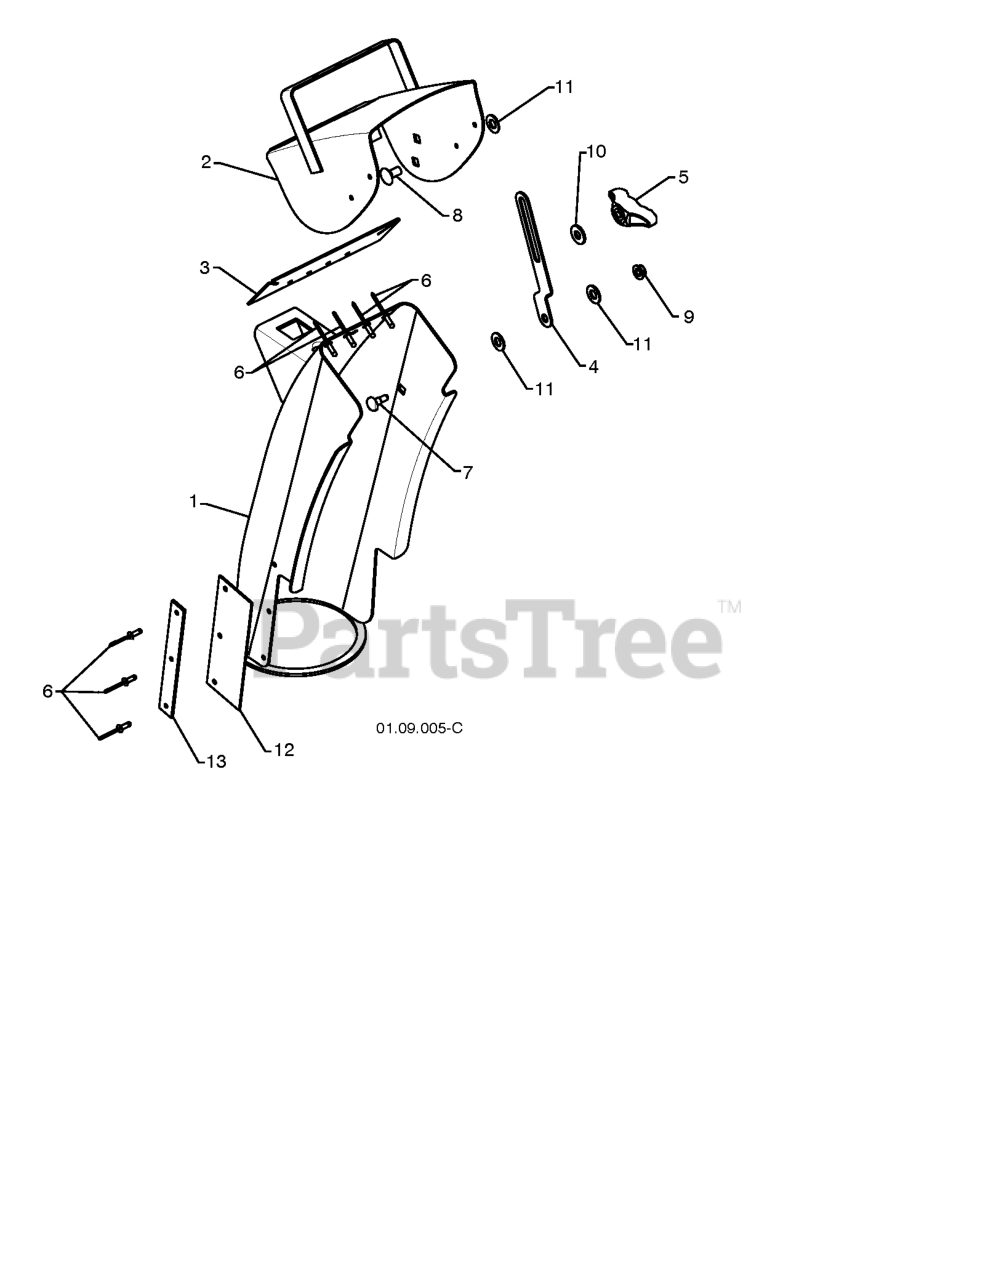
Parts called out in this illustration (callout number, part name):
1	CHUTE.WELDMENT
2	DEFLECTOR.WELDMENT.PNT.ORANGE
3	SEAL.DEFLECTOR
4	STRAP, CHUTE
5	KNOB, DEFLECTOR
6	RIVET BLIND
7	SHOULDER BOLT
8	BOLT
9	NUT.HEX.FLANGE.1/4
10	WASHER.20X8.5
11	WASHER, NYLON FRICTION
12	SHIELD.SNOW.CHUTE
13	STRAP.SHEILD.RETAINER
